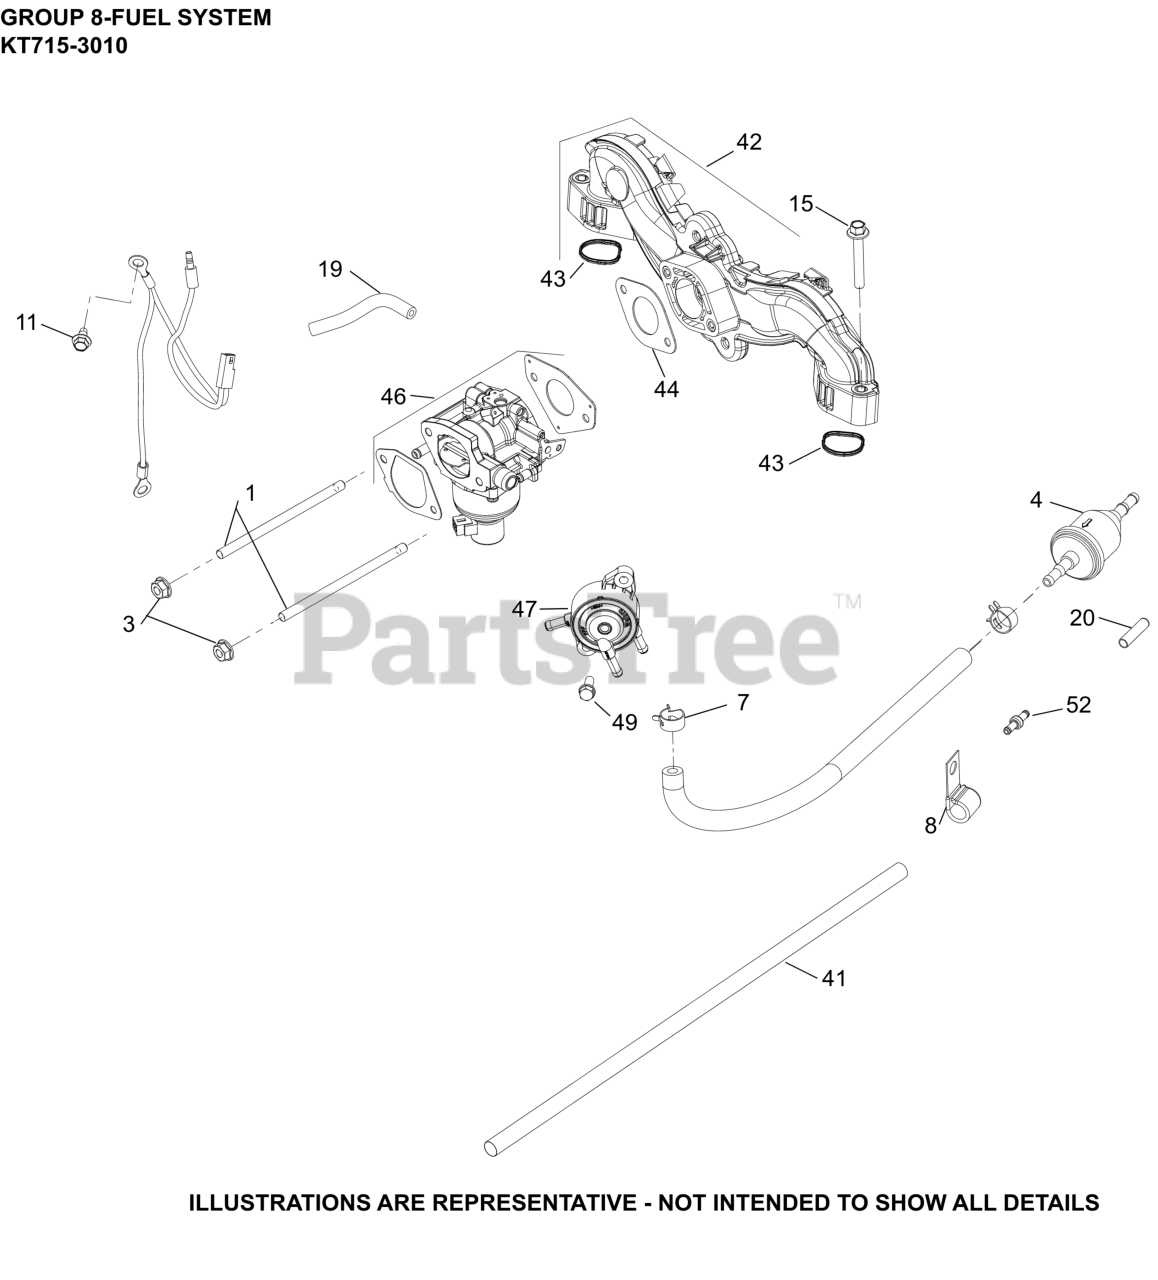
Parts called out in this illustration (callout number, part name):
3	NUT, FLG M6X1.0
4	FILTER,FUEL 51 MICRON (FUEL PUMP)
7	SPRING CLAMP, HOSE
8	CLIP, CABLE (KM)
11	SCREW, THREAD FORMING
15	SCREW, FLG M6X1.0X40
19	HOSE, EVAPORATIVE 20"- (#24326143S)
20	CAP, MASKING
41	SLEEVE, ANTI-ABRASION
42	INTAKE MANIFOLD W/GASKETS
43	O-RING, INTAKE PORT
44	GASKET, CARBURETOR (PIM, CV)
46	KIT,CARB (NIKKI)
47	PUMP, FUEL (PULSE)
49	SCREW, HEX HEAD
52	FITTING, FUEL SYSTEM
NI	KIT, HIGH ALT (4000-8000 FT)(NIKKI)
NI	KIT, OVERHAUL NIKKI G-TYPE TWIN
NI	KIT, BOWL WITH O-RINGS NIKKI G-TYPE TWIN
NI	KIT, FLOAT AND NEEDLE NIKKI G-TYPE TWIN
NI	KIT,CHOKEREPAIR NIKKI G-TYPE T-DISC.
NI	KIT,THROTTLE SHAFT(19MM)NIKKI-DISC.
NI	KIT, O-RING (NIKKI)
NI	KIT, SOLENOID (NIKKI)
